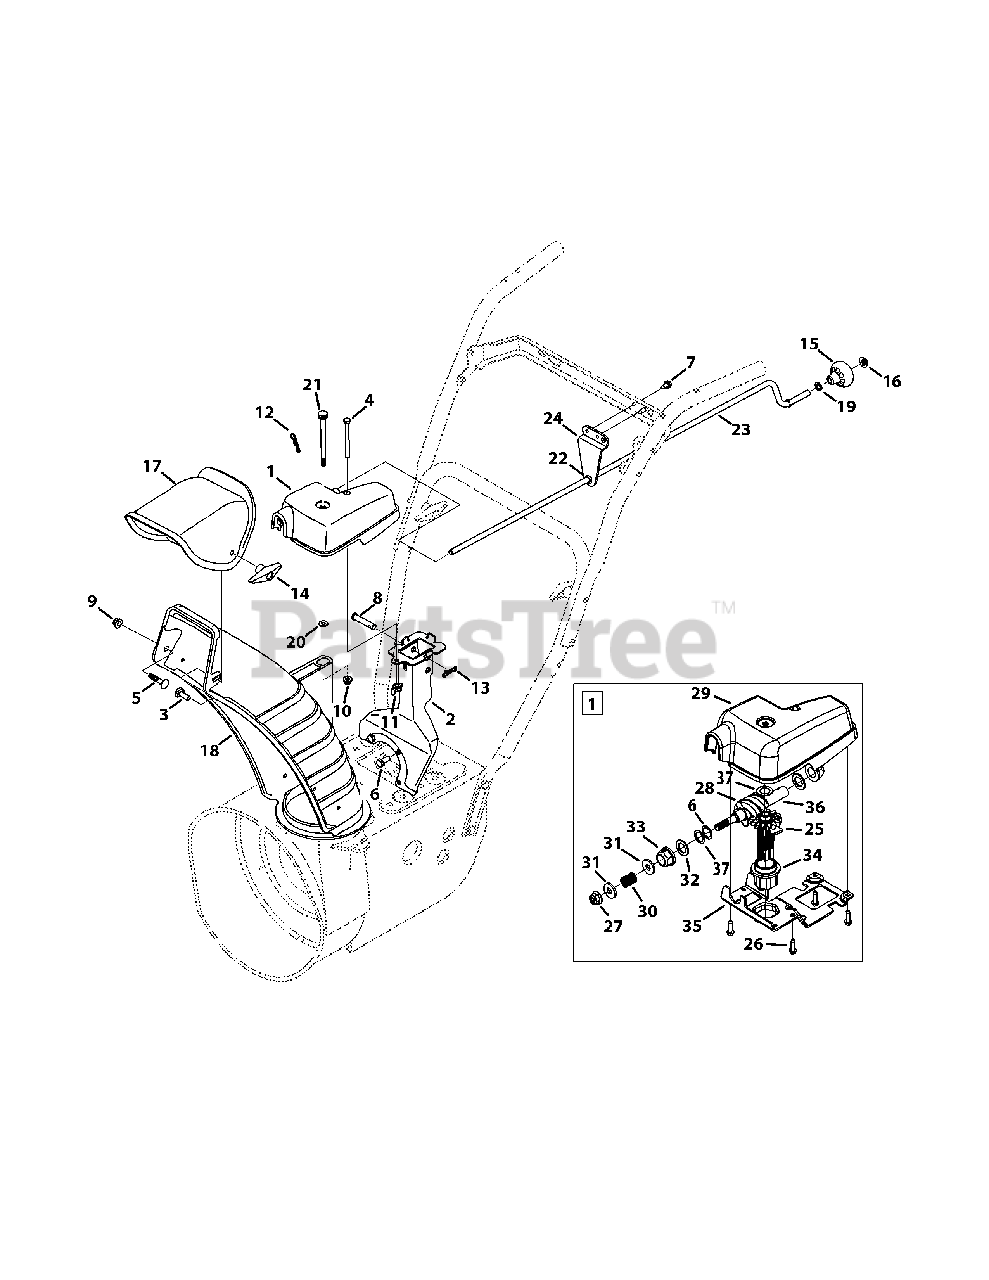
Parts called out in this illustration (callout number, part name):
1	Chute Rotation Gear Box
2	Chute Support Bracket (large block)
3	Carriage Bolt, 5/16-18 x 1.00
4	Hex Screw, 1/4-20 x 3.00
5	Carriage Bolt, 5/16-18 x .750
6	Shim Washer, .632 x 1.00 x .010
7	Hex Washer Screw, 1/4-20 x .625
8	Clevis Pin, 3/8-1.87
9	Flange Lock Nut, 5/16-18
10	Flange Lock Nut, 1/4-20
11	Wing Nut, 1/4-20
12	Cotter Pin, .08 x 1.42
13	Bow-tie Cotter Pin
14	Wing Knob, 5/16-18
15	Shift Knob, .390
16	Push Cap, 3/8
17	Upper Chute
18	Lower Chute, 5.0
19	Flat Washer, .375 x .738 x .063
20	Flaw Washer, .25 x .630 x .0515
21	Shoulder Screw, .312 x 3.5 x 1/4-20
22	Plastic Bushing, .380 ID
23	Chute Crank
24	Support Rod Bracket
25	Gear Assembly
26	Screw, 12-16 x .75
27	Flange Lock Nut, 3/8-16
28	Worm
29	Gear Cover
30	Compression Spring, .39 x .60 x .88
31	Flat Washer, .380 x .93 x .110
32	Flat Washer, .625 x 1.0 x .067
33	Hex Bearing
34	Flange Bearing
35	Gear Bracket
36	Worm Shaft
37	Shim Washer, .63 x 1.00 x .020
